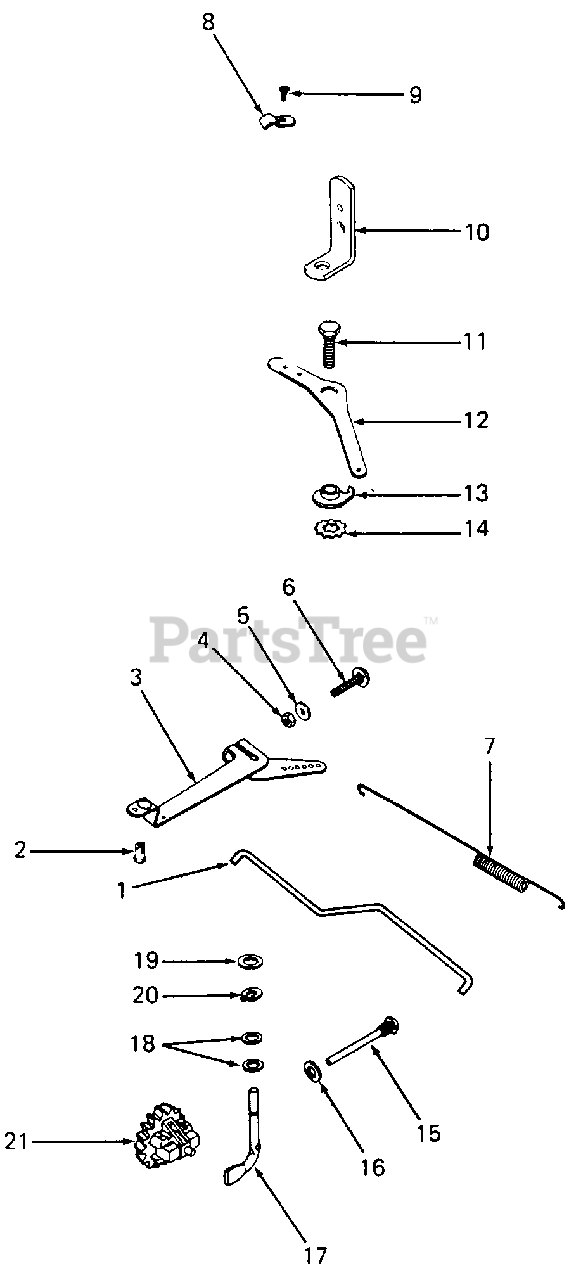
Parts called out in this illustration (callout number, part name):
1	Linkage, Governor
2	Bushing, Linkage Retaining
3	Arm, Governor
4	Nut, Hex, 1/4-20
5	Washer, Plain, 1/4
6	Screw, RH Sq Neck, 1/4-20 X 1.0 Lg
7	Spring, Governor
8	Clamp, Cable
9	Screw, Hex Cap, #10-24 X 7/16 Lg
10	Bracket, Throttle Cable
11	Screw, Hex Cap, 1/4-20 X .62 Lg
12	Lever, Speed Control
13	Stop, Governor
14	Washer, Lock
15	Pin, Governor Stop
16	Washer, Plain, 1/4
17	Shaft, Governor Stop
18	Washer, Plain, 1/4
19	Washer, Plain, 1/4
20	Retainer, Governor
21	Kit, Governor Gear
